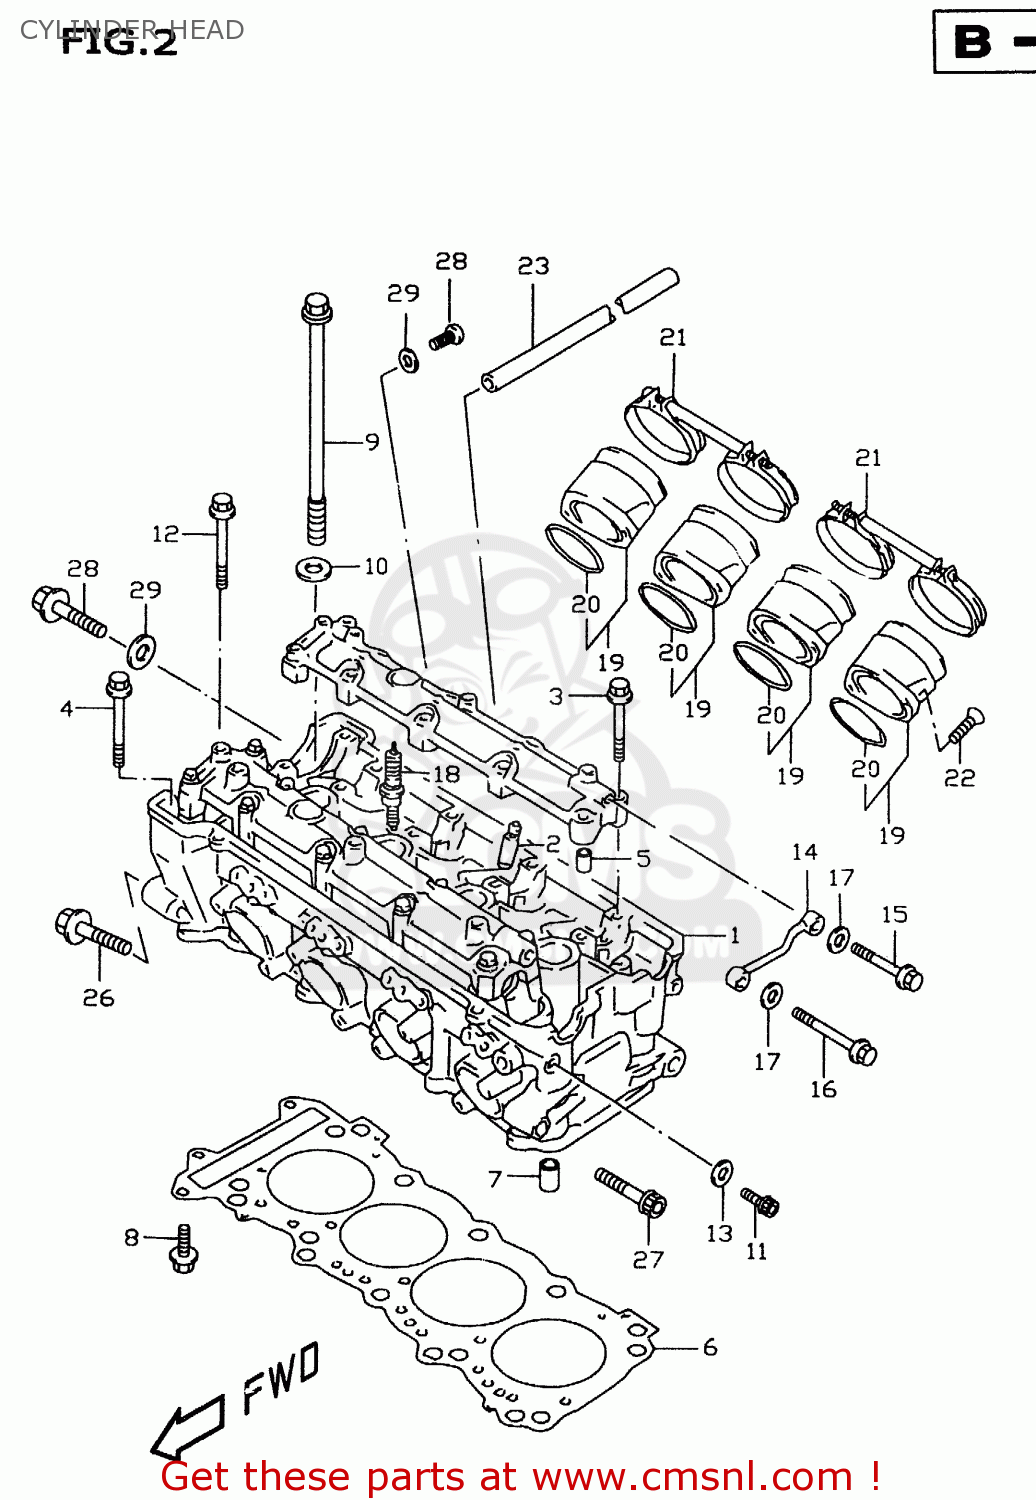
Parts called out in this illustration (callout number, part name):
1	HEAD SET,CYLINDER
2	GUIDE,VALVE
3	BOLT(6X39)
4	BOLT(6X45)
5	PIN(6.2X8X16)
6	GASKET,CYLINDER HEAD
7	PIN
8	BOLT
9	BOLT(10X160)
10	WASHER(10.5X19X2)
11	BOLT
12	BOLT,CYL.OIL P
13	GASKET(5.8X13X1.2) (NAS)
14	PIPE,CYLINDER HEAD OIL
15	BOLT
16	BOLT (6X45)
17	WASHER
18	PLUG,SPARK(CR8E)
19	PIPE ASSY,INTAKE
20	O RING(D:2.4,ID:44)
21	CLAMP COMP,INTAKE PIPE
22	SCREW
23	HOSE(5X10X600)
24	BOLT
25	BOLT
26	BOLT,CYL HEAD SIDE FACE
27	WASHER,HEAD COVER
28	SCREW
29	GASKET(6.2X11X1).2 (NAS)
